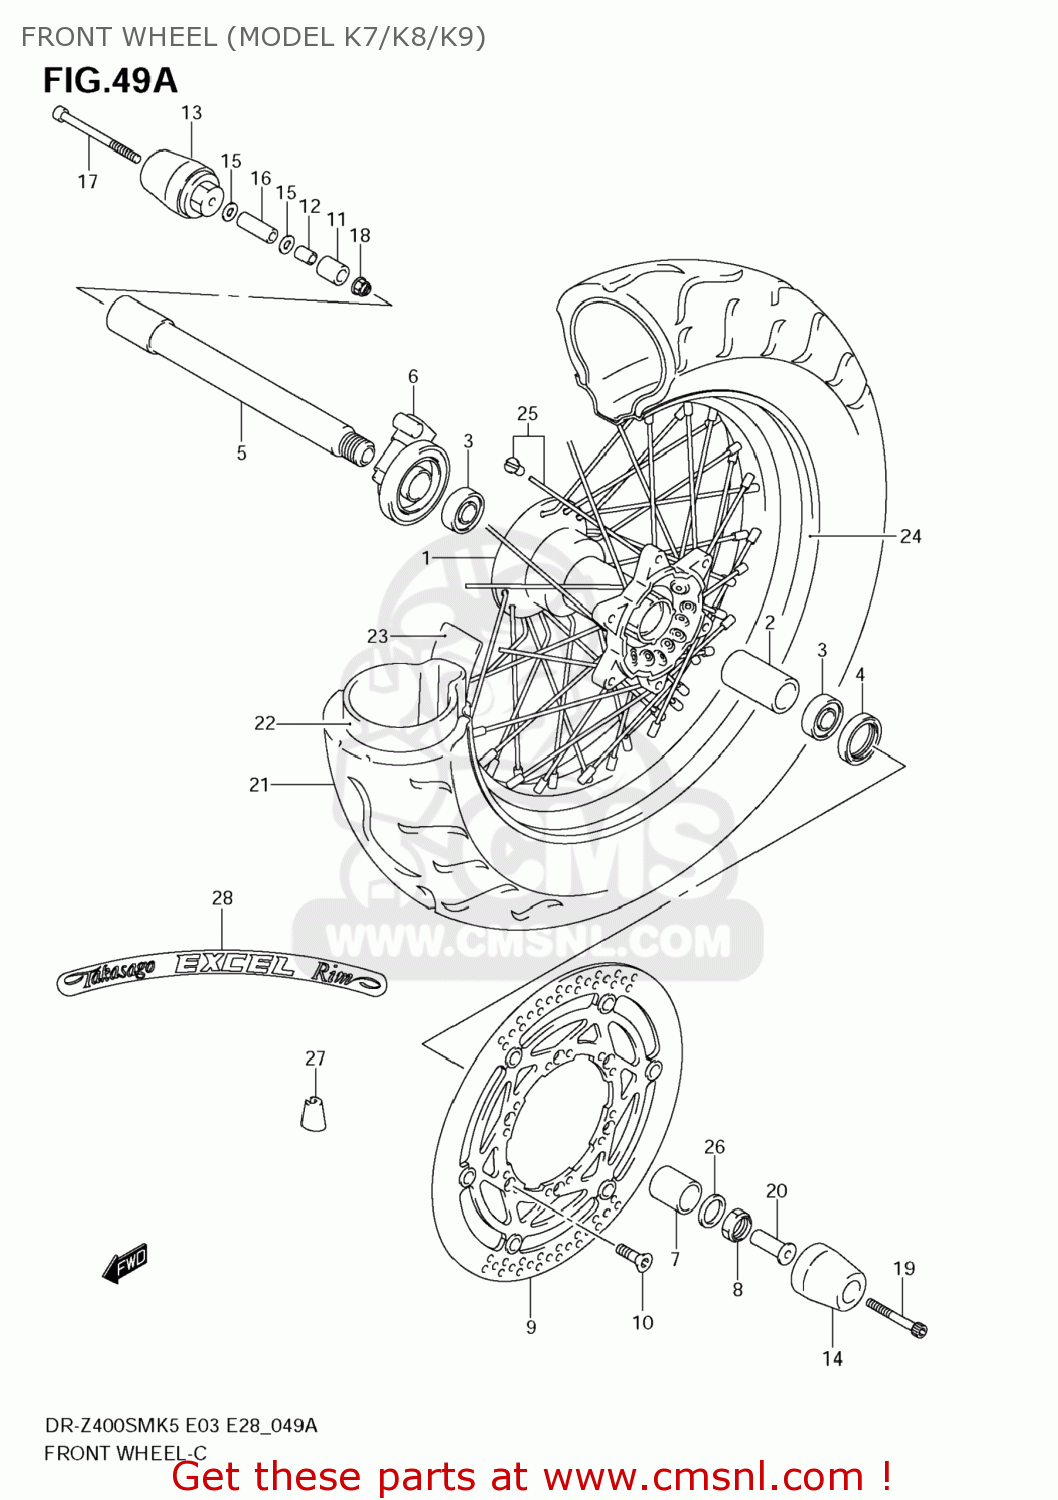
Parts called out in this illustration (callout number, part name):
1	HUB,FR WHEEL
2	SPACER,FR HUB BEARING
3	BEARING
4	SEAL,OIL(25X37X6)
5	AXLE,FR
6	BOX ASSY,SPEEDOMETER GEAR
7	SPACER,FR AXLE,L
8	NUT
9	DISC,FR BRAKE
10	SCREW(6X18)
11	EXPANDER,FR AXLE SLIDER,R
12	SPACER(5.5X8X10.5)
13	SLIDER,FR AXLE,R
14	SLIDER,FR AXLE,L
15	WASHER(5.5X12X0.8)
16	SPACER(5.5X9.5X26)
17	BOLT(5X65)
18	NUT
19	BOLT
20	NUT
21	TIRE,FR(120/70R17M/C 58H)
22	TUBE ASSY,WHEEL INNER
23	PROTECTOR,WHL INR TUBE
24	RIM,FR WHEEL(17XMT3.50 AL)
25	SPOKE SET,FR WHEEL
26	WASHER(18X26X2.8)
27	BALANCER,WHEEL(15G)
28	EMBLEM SET,EXCEL
